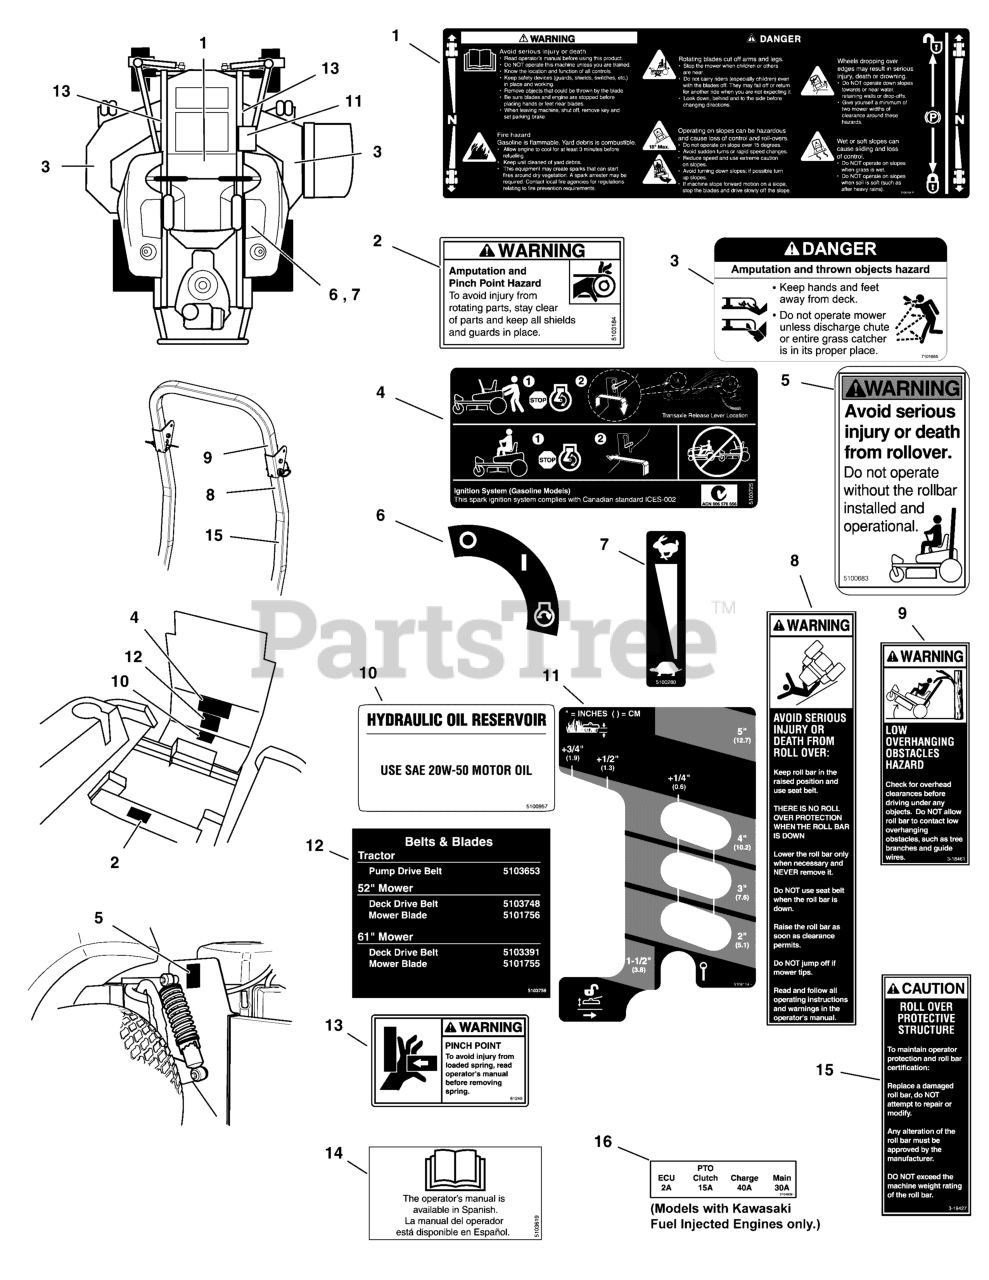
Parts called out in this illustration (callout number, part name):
1	DECAL, MAIN SAFETY
2	DECAL, WARNING, HAND IN BELT, ENG ONLY
3	DECAL, DANGER DO NOT OPERATE W/O DEFLECT
4	DECAL, TRANSAXLE RELEASE, 600/700
5	DECAL, WARNING, ROLL BAR
6	DECAL, IGNITION SWITCH
7	DECAL, THROTTLE CONTROL
8	DECAL, WARNING, FOLDING ROLL BAR
9	DECAL, WARNING OVERHANG, ROPS
10	DECAL, HYDRAULIC OIL, SAE 20W50
11	DECAL, CUTTING HEIGHT
12	DECAL, BELT & BLADE, IS700Z/ZTS700
13	DECAL, PINCH POINT
14	DECAL, MANUAL AVAIL IN SPANISH
15	DECAL, CAUTION, FOLDING ROLL BAR
16	DECAL, FUSE LOCATION, KAWI EFI
